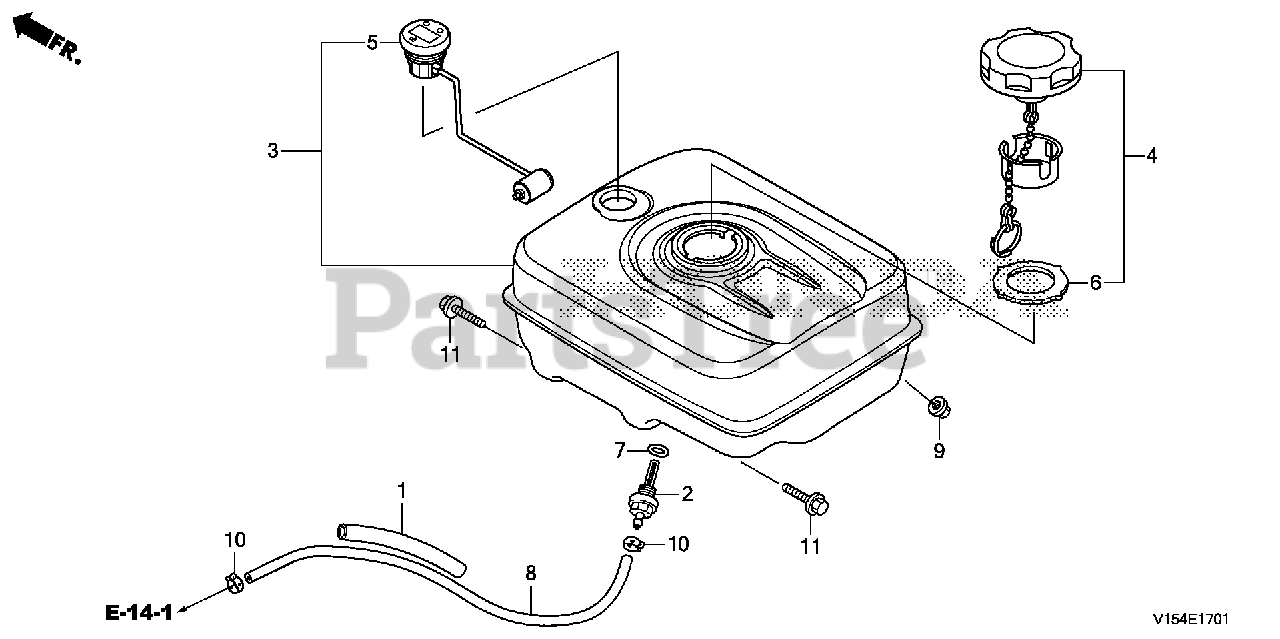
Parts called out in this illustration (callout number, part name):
1	RUBBER, SUPPORTER (107MM)
2	JOINT, FUEL TANK
3	TANK ASSY., FUEL *R280* (GAUGE) (POWER RED)
4	CAP, FUEL FILLER
5	GAUGE ASSY., FUEL
6	GASKET, FUEL FILLER CAP (39X62X3) (RADICON)
7	O-RING (13.5X1.5) (ARAI)
7	O-RING (14MM) (NOK)
8	TUBE, FUEL (4.5X235) (FKM)
9	NUT, FLANGE (8MM)
10	CLAMP, TUBE (D8)
11	BOLT, FLANGE (8X28)
